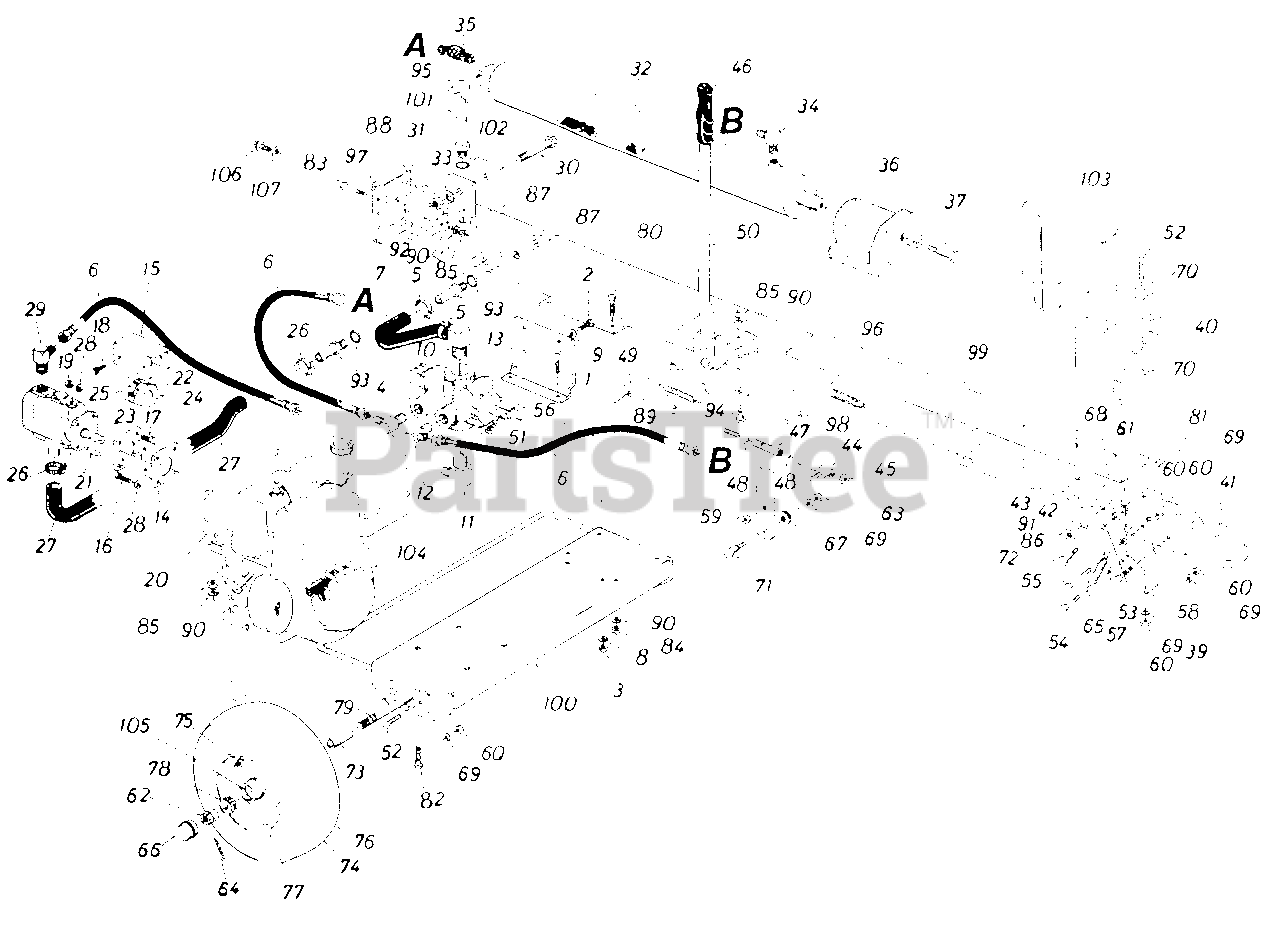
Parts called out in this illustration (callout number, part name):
1	Hex Bolt 5/16-18 x .75" Lg.
2	Hex Bolt 3/8-16 x .60" Lg.*
3	Hex Nut5/16-18 Thd.*
4	Control Valve 400
5	Hose Clamp 5/8"
6	High Pressure Hose Ass'y .38" I.D
7	R etu rn H ose-Valve to Tank 3/4" I.D.
8	L.-Wash. 5/16" I.D.*
9	L.-Wash. 3/8" I.D.*
10	Return Elbow
11	90ø Solid Male Adapter
12	90ø Solid Male Adapter
13	Valve Mtg. Plate
14	Coupling Support Brkt Ass'y.
15	Coupling Shield
16	Hex Bolt 5/16-24 x 1.00"*
17	Hex Bolt 5/16-24 x .75" Lg.*
18	Hex Wash. Hd. Tap Scr. 1/4-20 x .38" Lg.
19	Hex Nut 5/16-24 Thd.*
20	Sq. Key 1/4" x 1/4" x 2.25" Lg.
21	Pump with Woodruff Key - (642)
21	Pump with Woodruff Key - (645)
22	Spider L-0-90
23	SetScr. 1/4-20 x .25" Cup
24	Coupling Half 1.00" I.D.
25	Coupling Half .50" I.D.
26	Hose Clamp 5/8"
27	Suction Hose 1.0" Dia
28	L.-Wash. 5/16" I.D.*
29	90ø Solid Male Adapter
30	Hex Bolt 3/4" x 4.0" Lg.
31	Hex Nut 3/4" Thd.*
32	Hydraulic Cylinder 3-1/2" Dia. (642)
32	Hydraulic Cylinder 4" Dia. (645)
33	L.-Wash.3/4" I.D.*
34	90ø Male Adapter 3/4-16 MJ 3/8-16 NPT
35	45ø Male Adapter 3/4-16 MJ 3/8-18 NP
36	Pusher Plate (642)
36	Pusher Plate (645)
37	Shoulder Bolt .62" Dia. x 4.75" Lg. (1/2-13 Thd.)
39	Flip Stand Bracket
40	Chain-Tow Hitch
41	Tow Hitch Ass'y. Comp
42	Stand Pivot Bracket
43	Tow Hitch Brk't. 2 x 3/16 x 10.25" Lg. I N
44	Ferrule Ass'y.
45	Hex Cent. L.-Nut 3/8-24 Thd.
46	Grip-Black Vinyl
47	Compression Spring
48	Special Washer .378 x 1.00" x .125 Thd.*
49	Engagement Rod 3/8" Dia. x 9.0" Lg.
50	Engagement Handle
51	Hex Bolt 1/4-20 x 1.75" Lg.*
52	Hex Bolt 3/8-24 x 1.00" Lg.*
53	HexBolt3/8-24x.75" Lg.*
54	Hex Bolt 1/4-28 x 1.00" Lg.*
55	Hex Bolt 3/8-24 x 1.75" Lg. (Grade 5)
56	Hex Patch L.-Nut 1/4-20 Thd .
57	Hex Cent. L.-Nut 1/4-28 Thd.
58	Hex Nut 1/4-28 Thd.
59	Hex Cent L.-Nut 5/16-18 Thd.
60	Hex Nut 3/8-24 Thd.*
61	Hex Nut 5/16-19 Thd.*
62	Hex Castle Nut 3/4-16 Thd.
63	Hex Nut 3/8-16 Thd.*
64	Cotter Pin 5/32" Dia. x 1.25" Lg.*
65	Extension Spring .50" O.D. x 3.97." Lg.
66	Hub Cap
67	Rubber Washer
68	L.-Wash. 5/16" I.D.*
69	L.-Wash. 3/8" I.D.*
70	Fl.-Wash. .375" I.D. x .870" O.D. x .090
71	ShouIder Bolt .498" Dia. x x.340" Lg.
72	Shoulder Bolt .437" Dia. x .268" Lg.
73	Spacer .75" I.D. x 1.12" O.D. x 1.56" Lg.
74	Wheel Ass'y. Comp. 16.0 x 4.0"
75	Air Valve-Tubeless
76	Tire Only 16.0 x 4.0-2 Ply
77	Wheel Rim Ass'y Only
78	Roller Rearing 3/4" I.D
79	Axle Ass'y. .75" Dia. x 35.25" Lg.
80	Hex Bolt 5/1 6-24 x 1 .00 0 Lg.*
81	Hex Bolt 5/8-18 x 3.50" La.*
82	Hex Bolt 5/16-24 x 1.75 0 Lg.*
83	Hex Bolt 5/16-18 x 1.50" Lg.*
84	Hex Nut 5/16-24 Thd.*
85	Hex Nut 5/16-18 Thd.*
86	Hex Nut 5/8-18 Thd.*
87	Hex Nut 11/16-12Thd
88	Gasket 2.62 x 5.12
89	Extension Spring .50" O.D. x 4. 25" Lg.
90	L.-Wash. 5/16" I.D.*
91	L.-Wash 5/8" I.D.*
92	Fl Wash. 341' I.D. x .68" 0. D . x .062 Thk.
93	Adapter 1.0" Tube 11/16-12 O Ring
94	Shoulder Bolt .437" Dia. x .180" Lg.
95	Oil Fill Cap
96	Strainer Tube Ass'y
97	End Plate
98	Engagement Brk't. 1.39 x 1 1.75" Lg.
99	Complete Oil Tank Ass'y.
100	Engine Frame Ass'y.
101	Filler Tube Ass'y
102	O-Ring 92" I.D. x 1.16" O.D. x .116 Dia
103	Wedge Ass'y
104	5 H.P. Engine
104	8 H.P. Engine
105	Bearing Seal
106	Hex H d. Tap Scr. 5/16 "
107	Gasket
